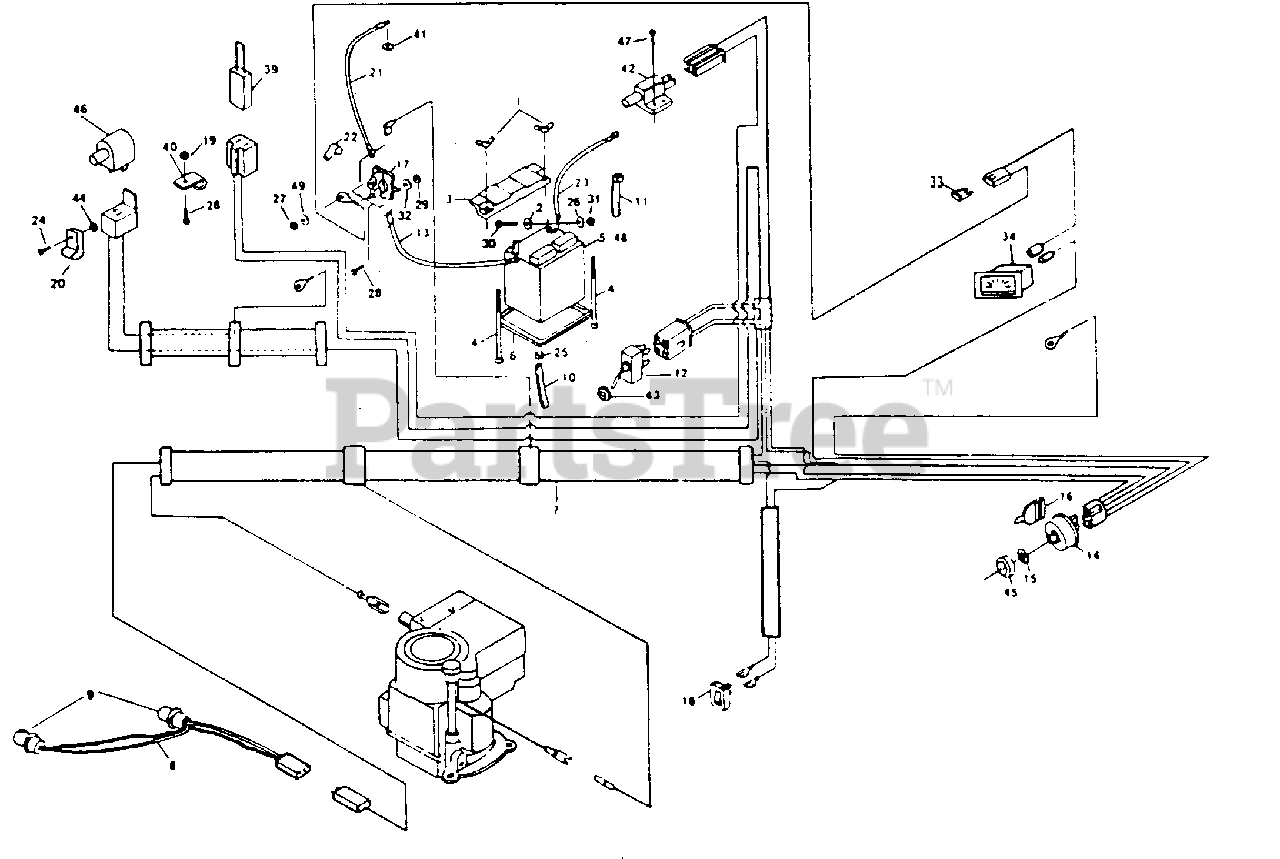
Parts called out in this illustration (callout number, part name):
1	Wing Nut 1/4-20 (AYP part number)
2	Washer 9/32 x 5/8 x 16 Ga. (AYP part number)
3	Terminal Guard (AYP part number)
4	Carriage Bolt (AYP part number)
5	12V Battery (Shipped dry: purchase battery acid locally) (AYP part number)
6	Battery Tray (AYP part number)
7	Ignition Harness
8	Light Socket Harness (AYP part number)
9	Light Bulb (AYP part number)
10	Battery Tube Tray (AYP part number)
11	Cable Tie (AYP part number)
12	PTO Switch (AYP part number)
13	Battery Cable (Battery to Solenoid) (AYP part number)
14	Ignition Switch (AYP part number)
15	Ignition Nut (AYP part number)
16	Key (AYP part number)
17	Solenoid (AYP part number)
18	Light Switch (AYP part number)
19	Hex Nut 1/4-20 (AYP part number)
20	Wire Clip (AYP part number)
21	Battery Cable (Solenoid to Starter) (AYP part number)
22	Terminal Cover (For Solenoid) (AYP part number)
23	Battery Cable (To Ground) (AYP part number)
24	Pan Head Screw (AYP part number)
25	Hose Clamp (AYP part number)
26	Lock Washer 1/4 (AYP part number)
27	Jam Hex Nut 1/4 x 20 (AYP part number)
28	Hex Bolt 1/4-20 x 1/2 Gr. 5 (AYP part number)
29	Keps Hex Nut 1/4-20 (AYP part number)
30	Hex Bolt 1/4-20 x 3/4 (AYP part number)
31	Hex Nut 1/4-20 (AYP part number)
32	Int. Tooth Lock Washer (AYP part number)
33	30 Amp Fuse (AYP part number)
34	Ammeter (AYP part number)
39	Wire Loop (AYP part number)
40	Insulated Clip (AYP part number)
41	Ext. Tooth Lock Washer (AYP part number)
42	Clutch Pedal Interlock Switch (AYP part number)
43	Hex Nut (AYP part number)
44	Keps Nut #10-32 UNF (AYP part number)
45	Ignition Bezel (AYP part number)
46	Plunger Switch (AYP part number)
47	Tapping Hex Screw (AYP part number)
48	Battery Caps Set (AYP part number)
49	Lock Washer (AYP part number)
